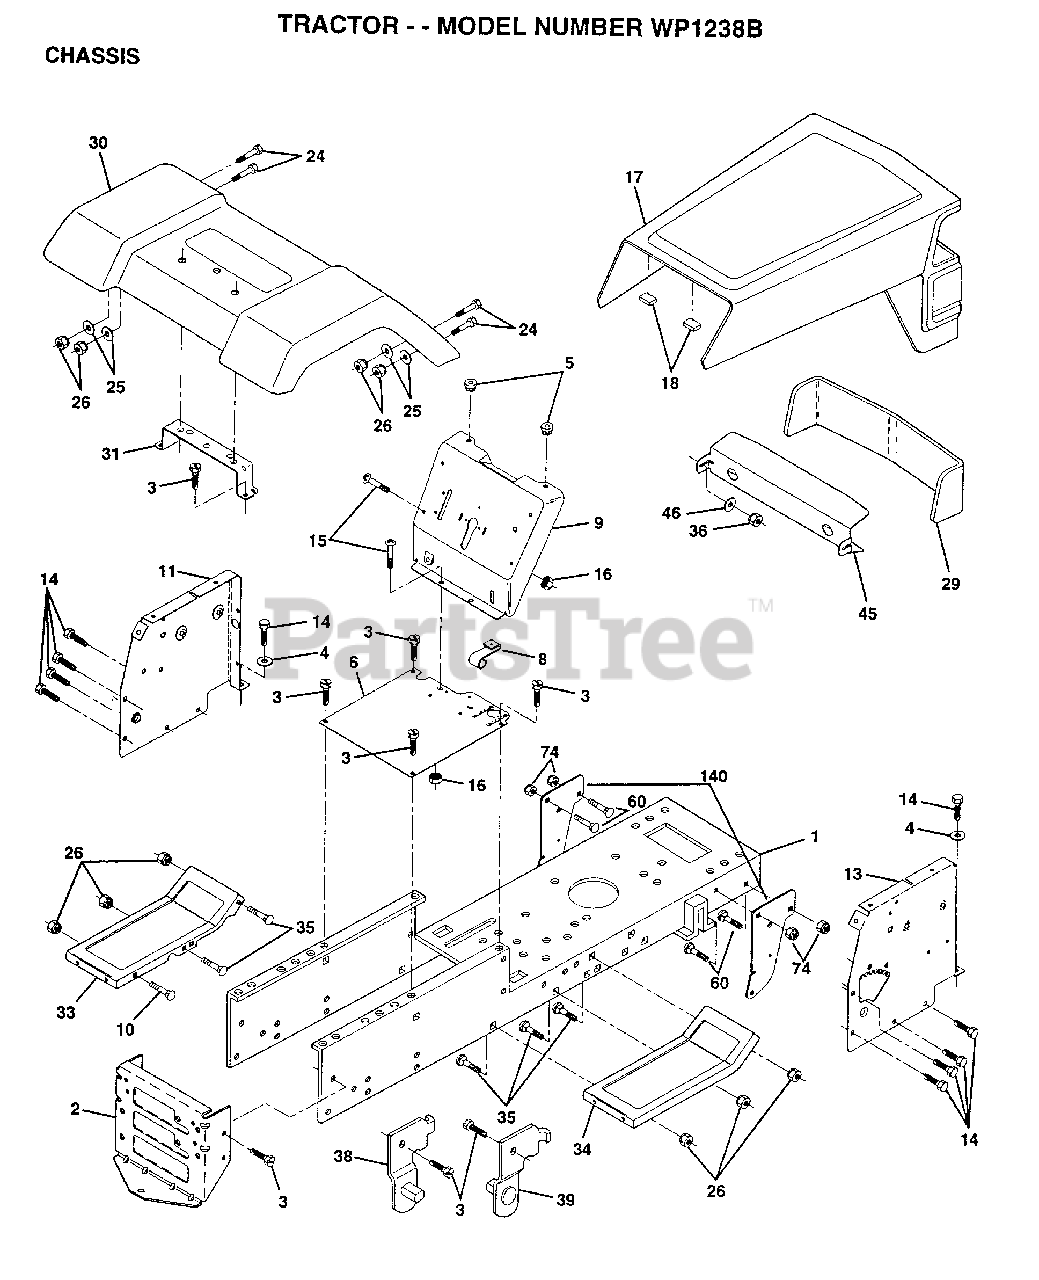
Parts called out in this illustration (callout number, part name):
1	CHASSIS WLDMT 11G
3	SCREW
4	WASHER
8	"CLIP,INSULATOR"
9	DASH.SLKSC.LT.1PC
11	PANEL.DASH.LH.
14	SCREW LT
15	SCREW
17	HOOD/GRILL ASM
24	BOLT
25	WASHER
26	NUT
29	LENS SERVICE KIT
30	FENDER
31	BRKT FENDER
33	FOOTREST LH
34	FOOTREST RH
35	BOLT
36	PAL NUT LT
38	BRACKET ASM LH
39	BRACKET ASM RH
46	RETAINER
60	BOLT
